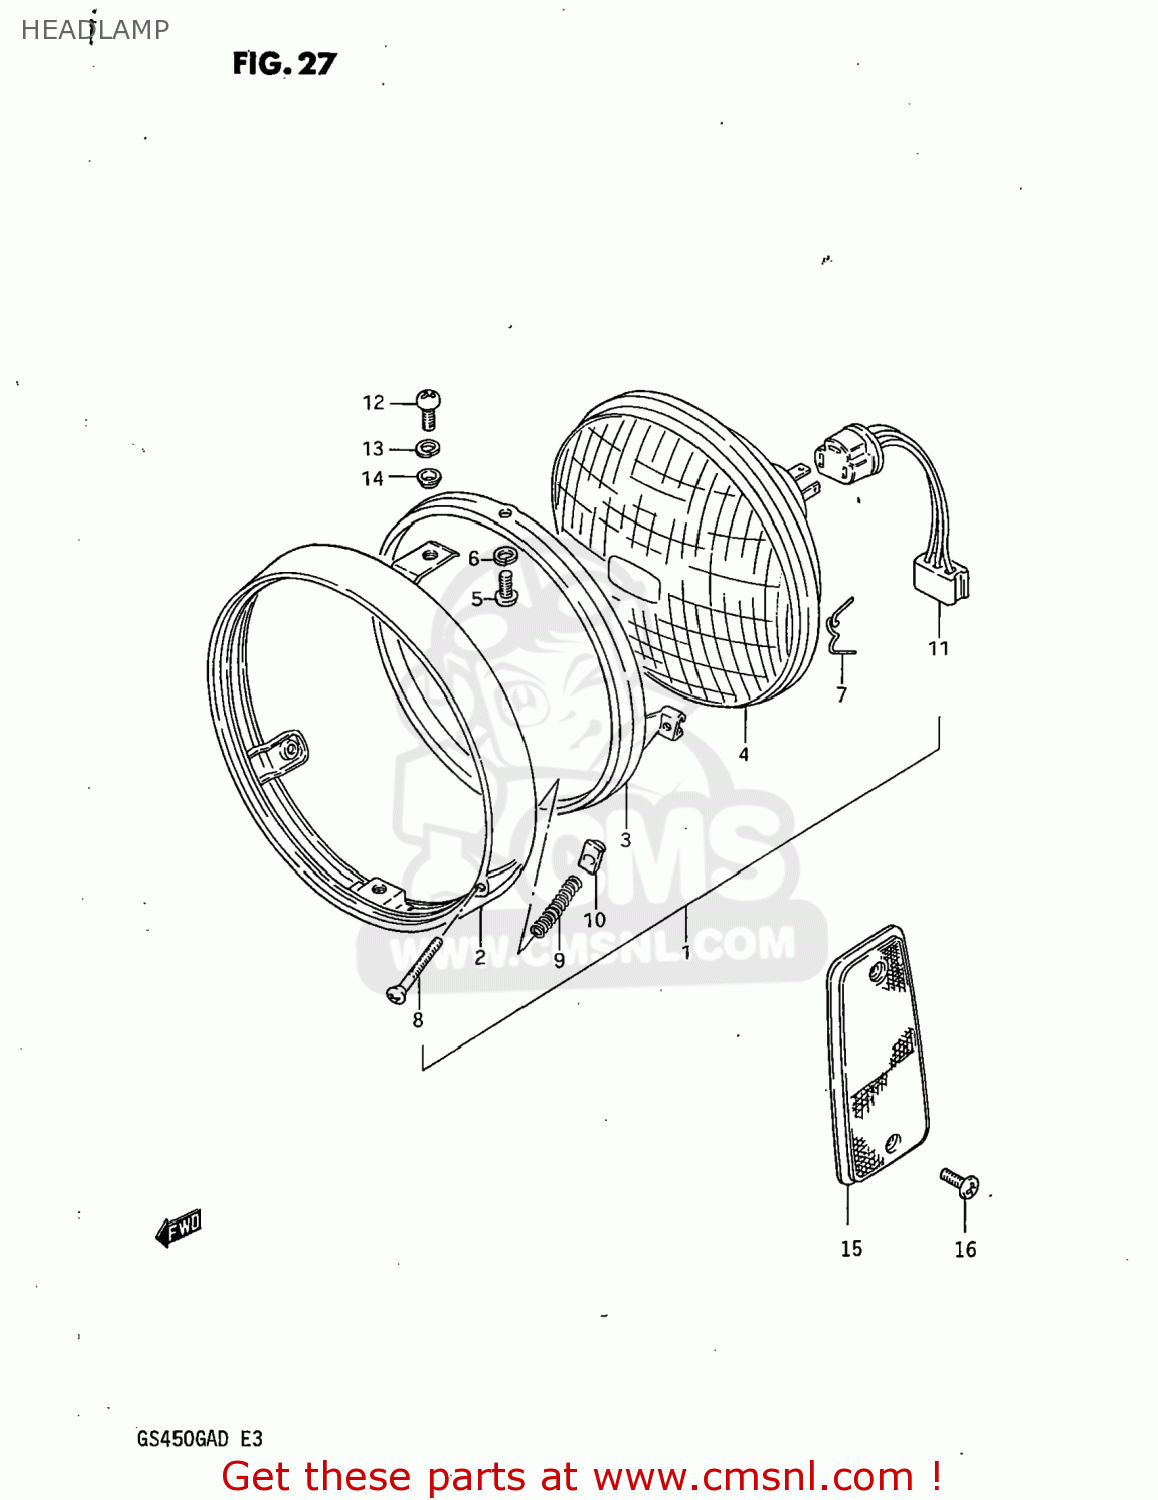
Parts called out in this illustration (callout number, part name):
1	HEADLAMP ASSEMBLY
2	RIM,HEADLAMP
3	RETAINER,HEADLAMP
4	LAMP UNIT
5	SCREW
6	LOCK WASHER
7	SPRING
8	SCREW,HEADLAMP ADJUST
9	SPRING
10	NUT
11	LEAD WIRE,HEADLAMP
12	SCREW
13	WASHER,LOCK
14	WASHER
15	REFLECTOR,REFLEX
16	SCREW 4X10
